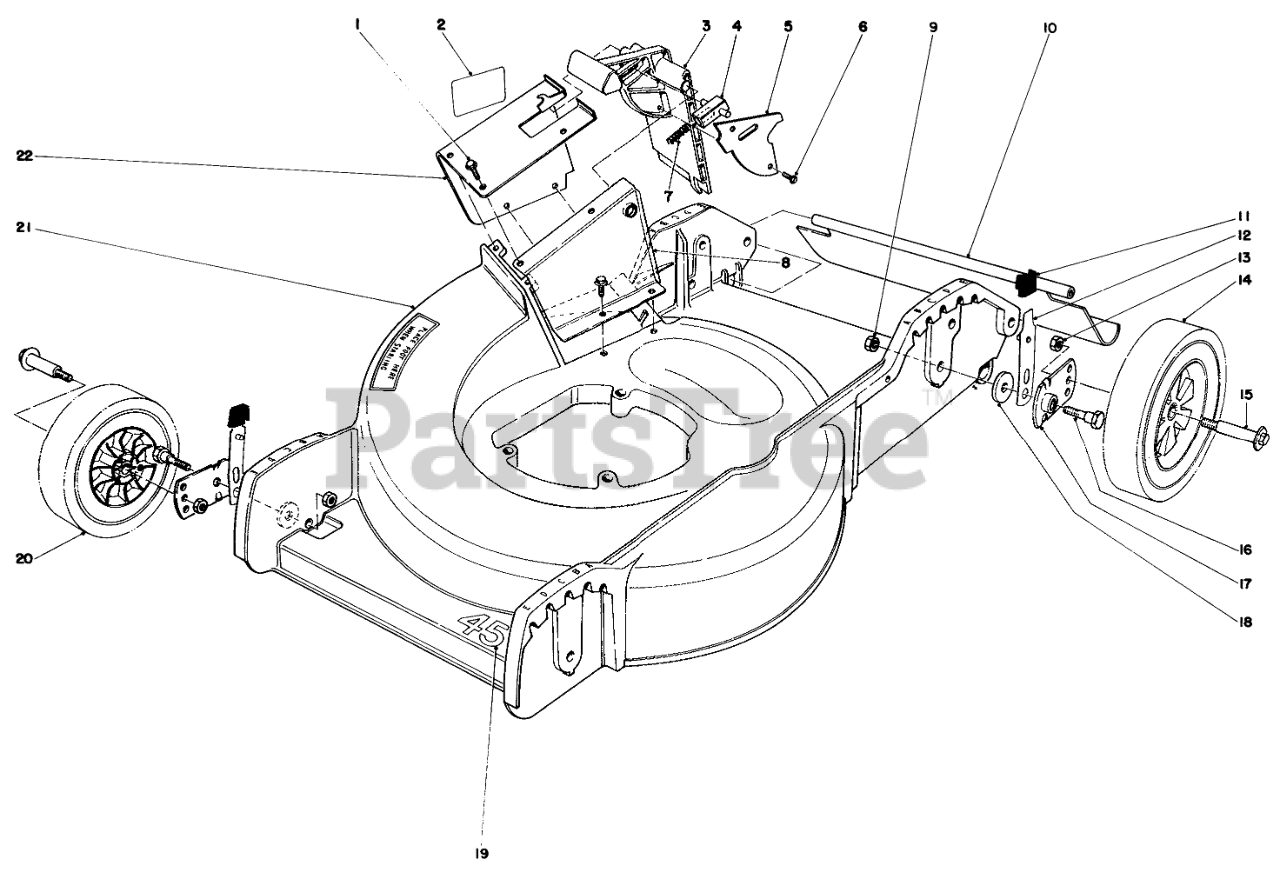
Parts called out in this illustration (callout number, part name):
1	SCREW
2	Decal-Door
3	Door Mulching
4	Door Latch
5	Cover Door
7	SPRING-COMPRESSION, LATCH
8	Inner Tunnel
9	Nut
10	SHIELD - TRAILING
11	KNOB-ARM
12	SPRING ARM ASM
13	Nut
14	WHEEL & TIRE ASM
15	BOLT-WHEEL
16	PIVOT SCREW
17	Pivot Arm
18	PIVOT WASHER
19	Decal
20	Wheel & Tire Assembly
21	Housing
22	Tunnel Outer
